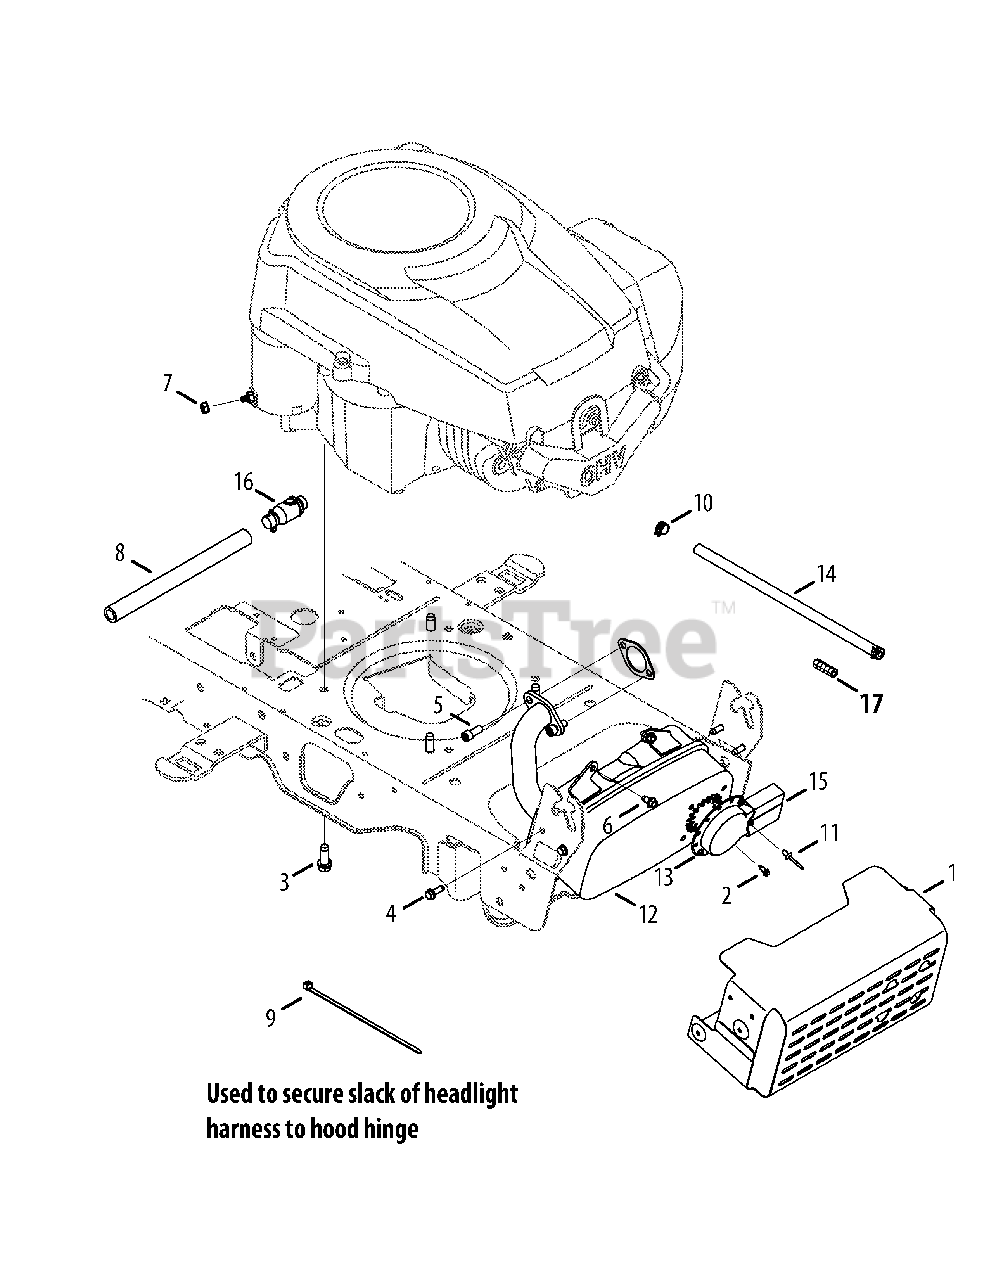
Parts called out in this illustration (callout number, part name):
1	Muffler Shield Assembly
2	Screw, Indented Washer, #8-18x0.500
3	Taptite Screw, 3/8-16x1.000
4	Taptite Screw, 1/4-20x0.500
5	Socket Head Screw, 5/16-18x.750
6	Taptite Screw, 1/4-20 x .625
7	Sems Nut, 1/4-20
8	Extension Hose, Oil Drain
9	Cable Tie, 3/16 x .05 x 7.4
10	Hose Clamp, .490 DIA.
11	Rivet, .188 DIA x .300 L
12	Muffler, EPA
13	Muffler Deflector†
14	Fuel Hose
15	Long Muffler Deflector, (EPA)
16	Oil Drain
17	Hose, Vent
